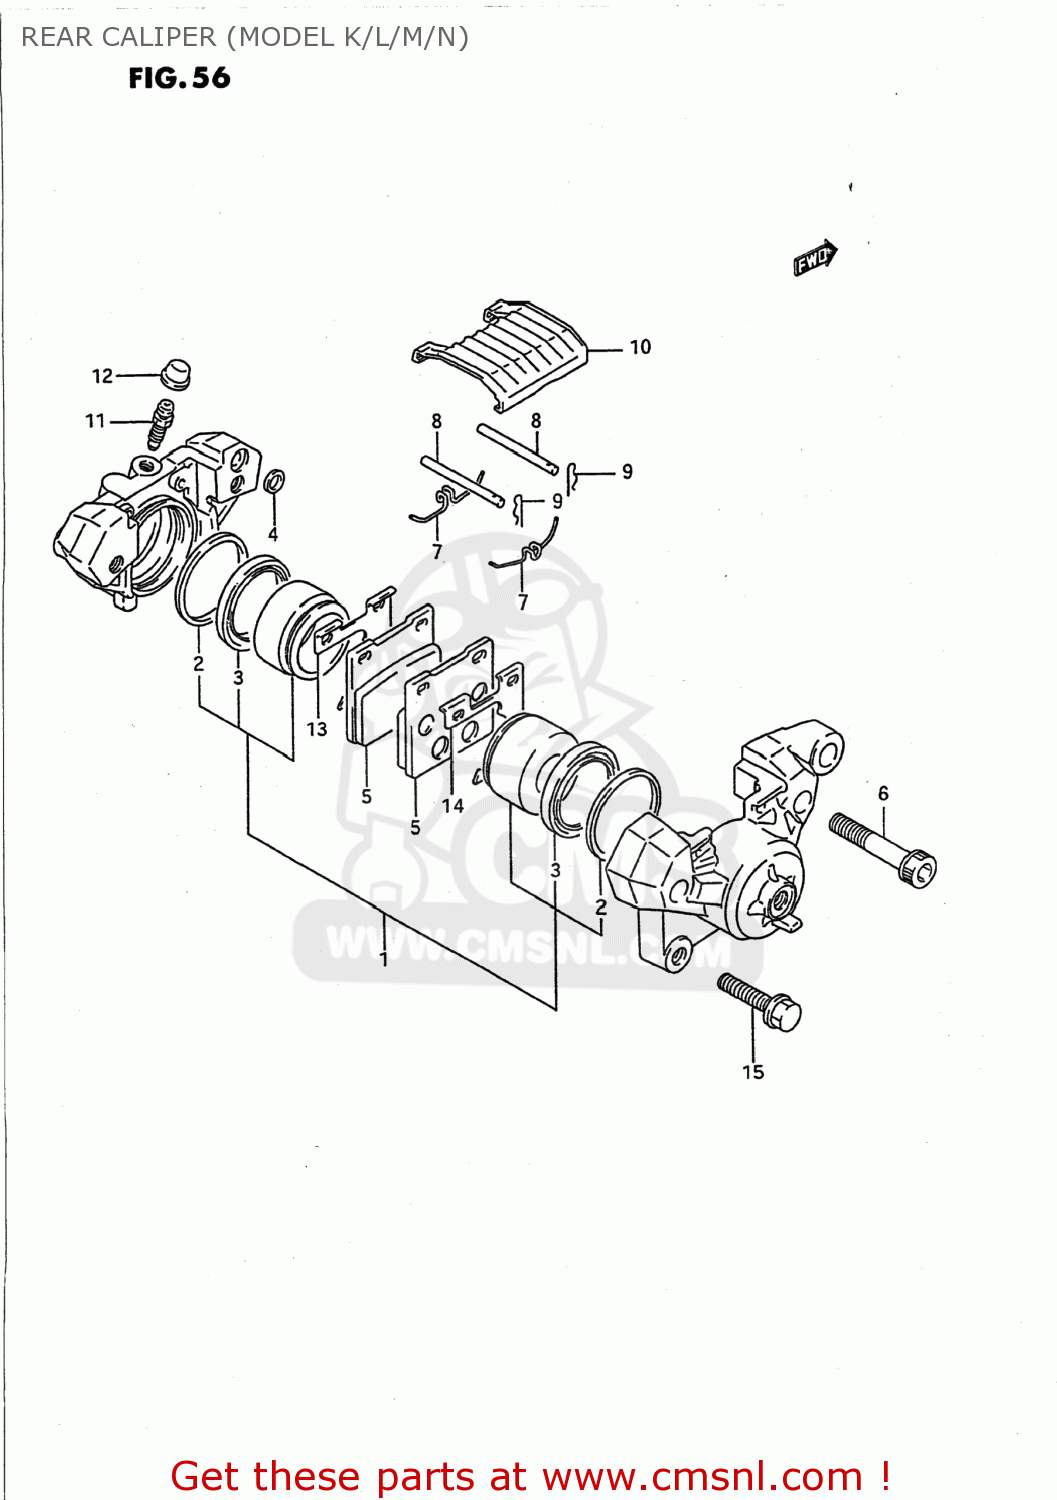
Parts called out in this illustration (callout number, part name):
1	PISTON SET
2	SEAL,PISTON
3	BOOT
4	SEAL,JOINT
5	PAD,BRAKE
6	BOLT
7	SPRING
8	PIN,PAD
9	CLIP,PAD PIN
10	COVER
11	BLEEDER
12	CAP,BREATHER
13	SHIM,INNER
14	SHIM,OUTER
15	BOLT
